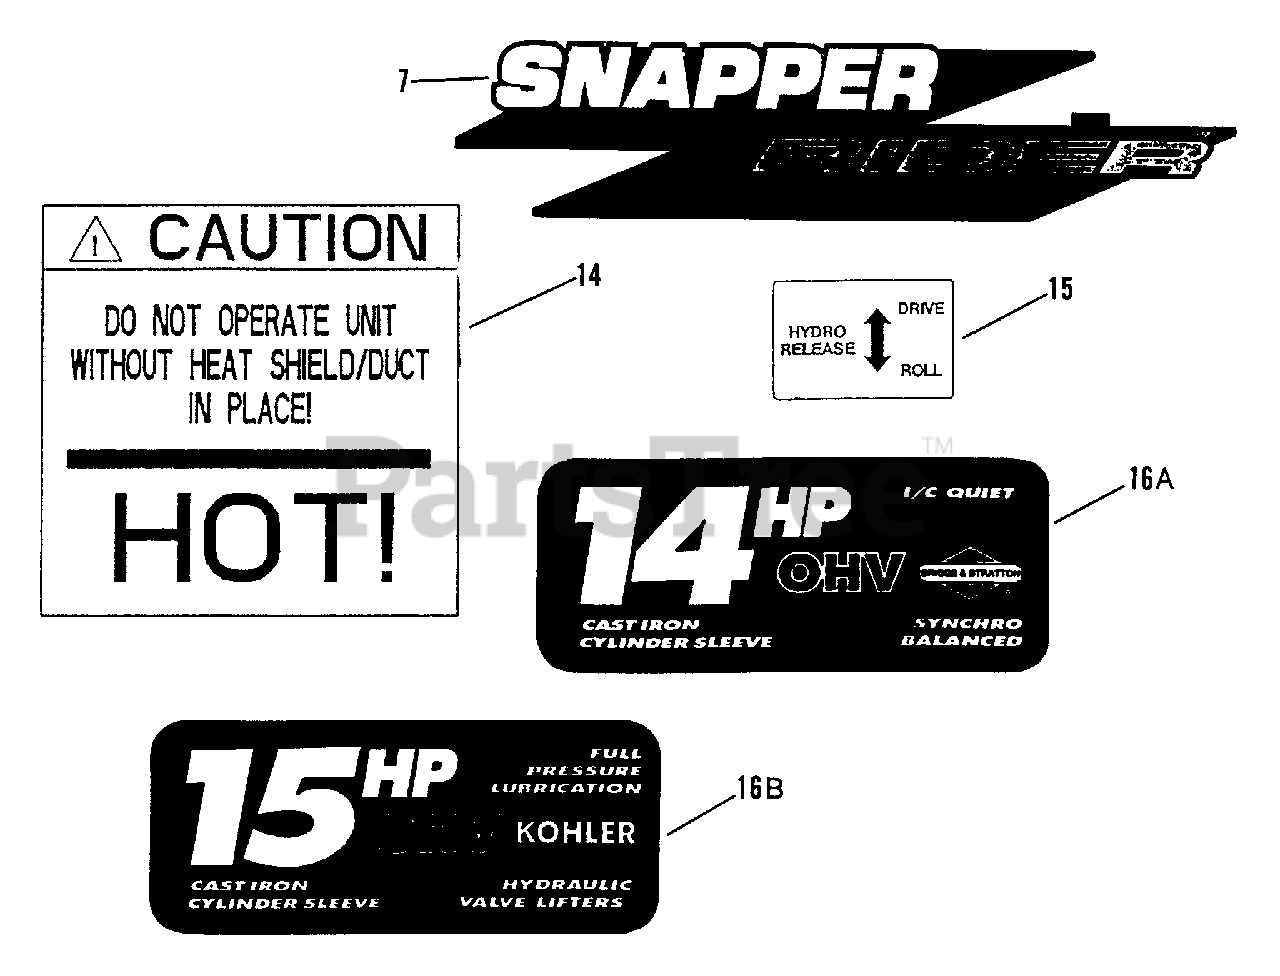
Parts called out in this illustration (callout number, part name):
7	DECAL, SNAPPER Z Rider (Steel Bodied Models)
14	DECAL, Heat Shield
15	DECAL, Hydro Release
16A	DECAL, Briggs 14HP Engine
16B	DECAL, Kohler 15HP Engine
